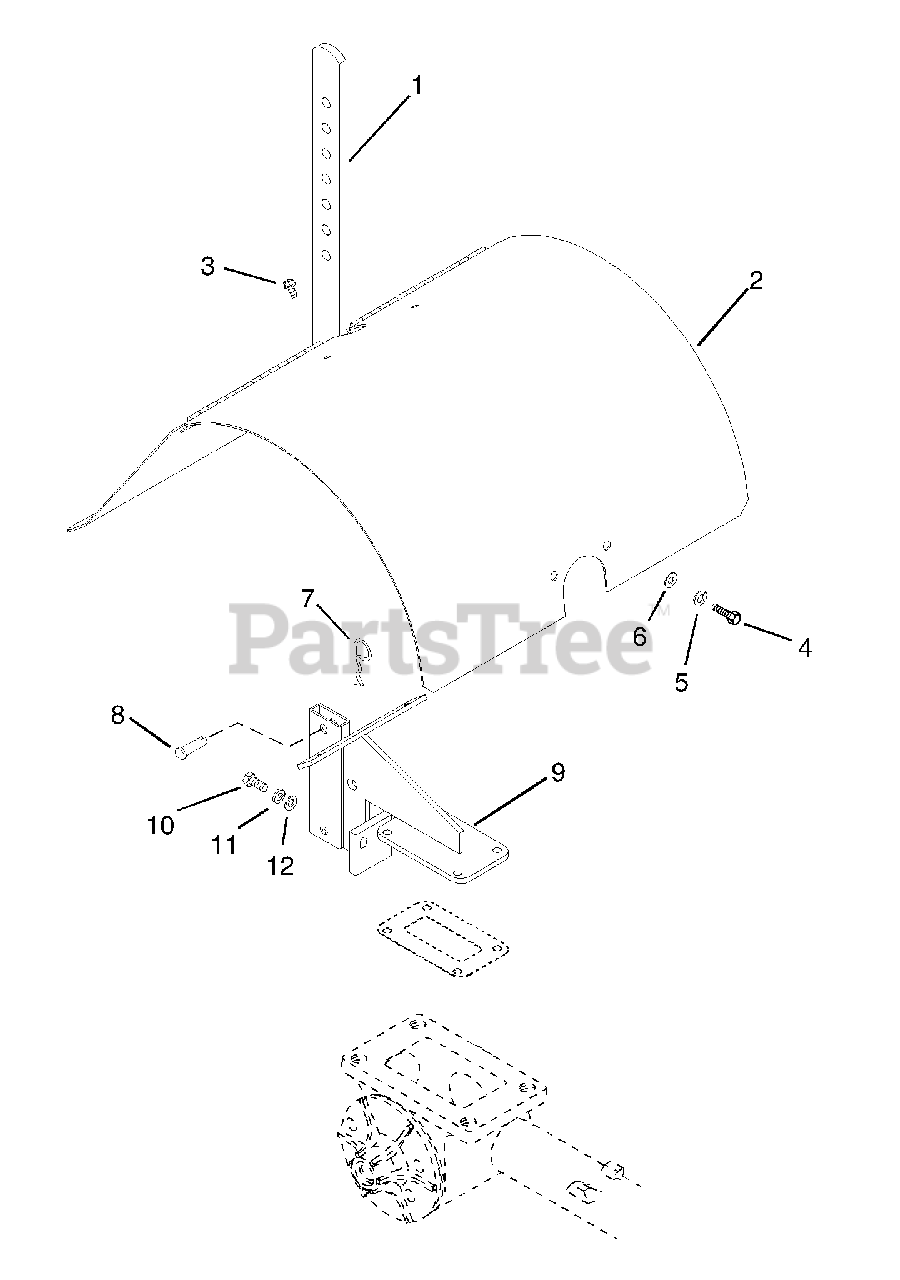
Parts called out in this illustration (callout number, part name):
1	DEPTH STICK
2	TINE HOOD W/ DECALS
3	@SCR-TAP .25-20X.50 HWH TR YWZ
4	@BLT-HEX .31-18X.50 GR5 YWZC
5	WSHR-LOCK INT .31 YWZC
6	@WSHR-FL-STL.312X.734X.065 YWZ
7	PIN-HAIR-EXT .12X.31X2.37 YWZC
8	PIN-CLEV .38 X 1.06
9	DEPTH STICK HOLDER
10	@BLT-HEX .31-18X1.00 GR5 YWZC
11	@WSHR-LK .31X.078 REG YWZC
12	@WSHR-FL-STL.344X.688X.065YWZC
